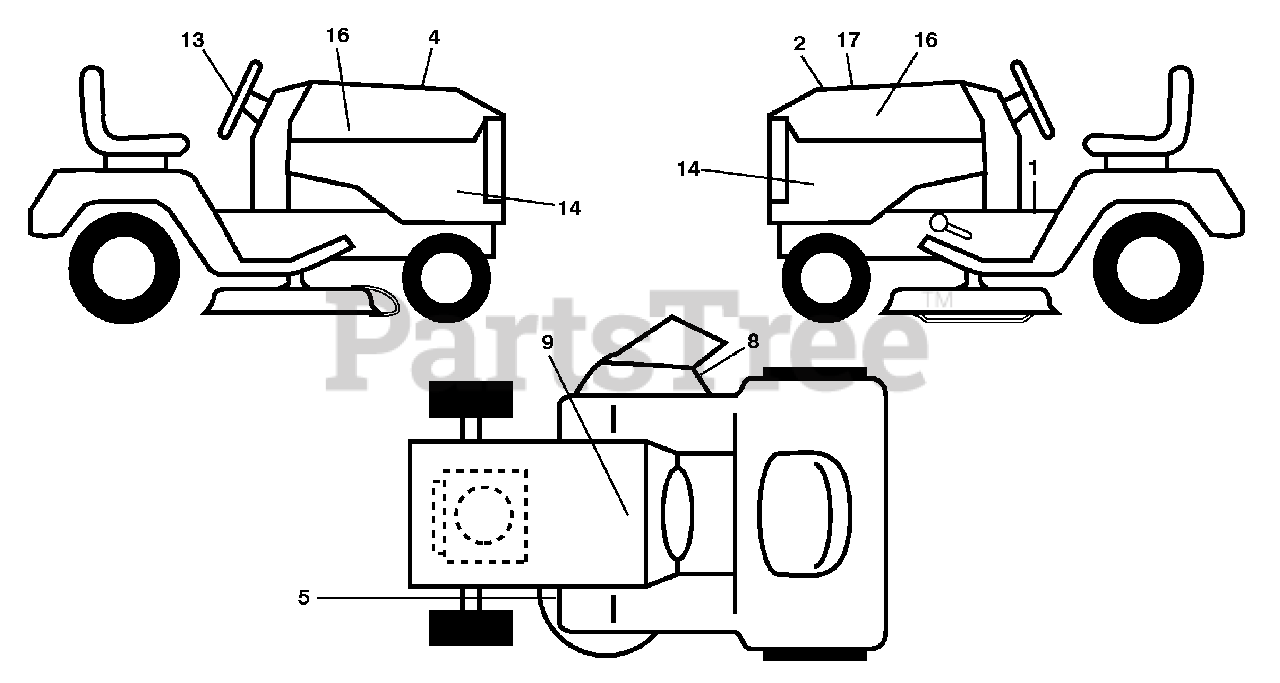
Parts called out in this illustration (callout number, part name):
1	Decal, Operator's
2	Decal, Hood Insert
4	Decal, Hood Cust. Resp.
5	Decal, Caution
8	Decal, Warning
13	Decal, Steering Whl
14	Decal, Panel Side
16	Decal, Hood Logo
17	Decal, Replacement
17	Decal, Bypass
